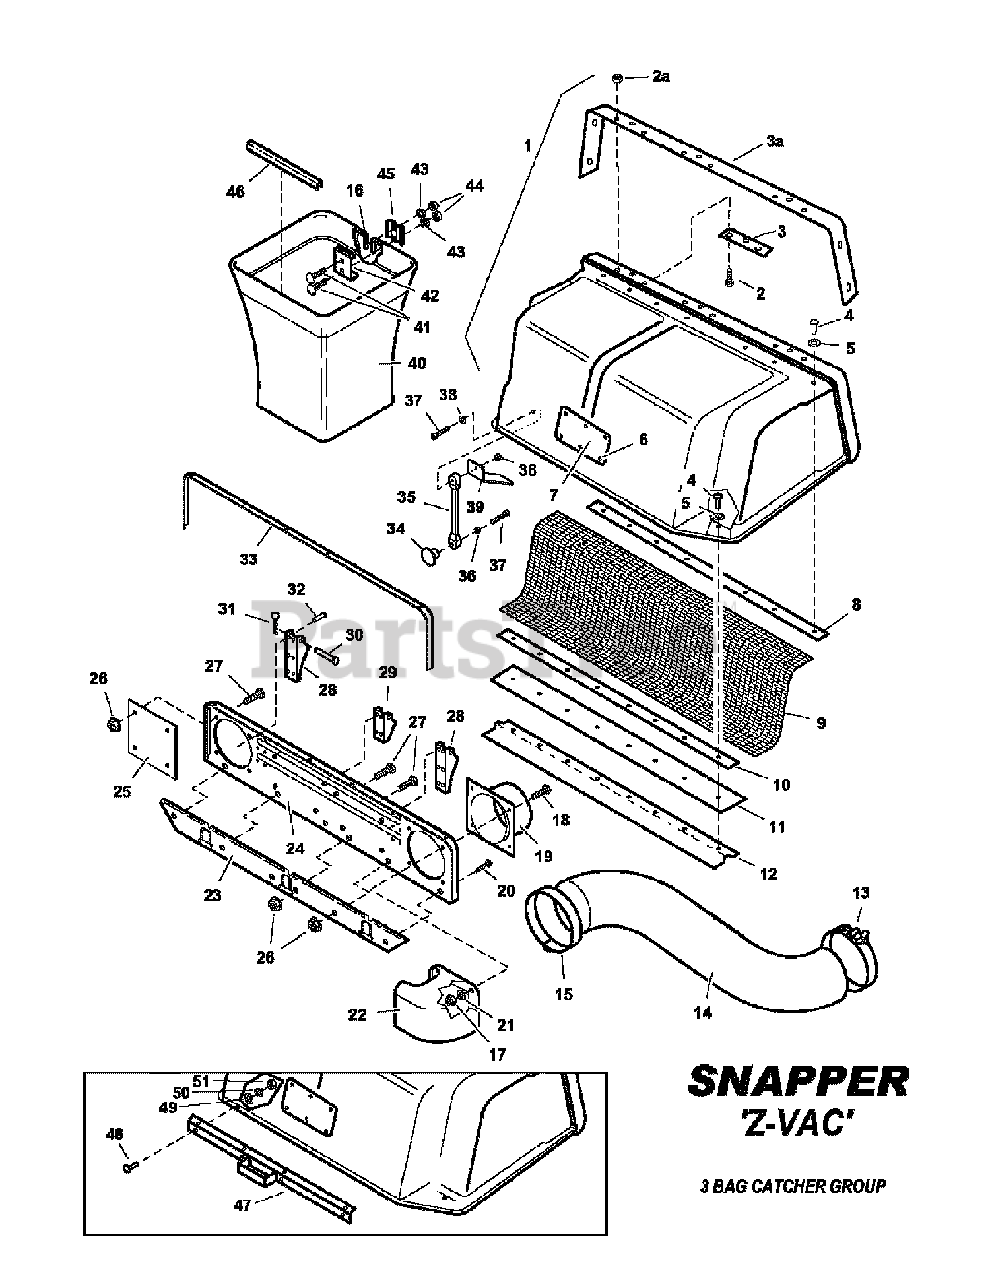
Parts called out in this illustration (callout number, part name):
1	ASSEMBLY, Cover & Screen
2	SCREW, 1/4-20 x 3/4" Hex Head Cap, GR5
2	SCREW, 1/4-20 x 5/8" Hex Head Cap, GR5
2A	NUT, 1/4-20 Hex Flange Lock, GR5
3	WELDMENT, Hinge
3A	STIFFENER, Hinge
4	POP RIVET, 3/16 x .565,Aluminum
5	* WASHER, Rivet .188 (.20 I.D. x .500 O.D.)
6	CLIP, Canoe
7	DECAL, Safety, Grass Bag
8	CLAMP
9	SCREEN, Catcher
10	CLAMP, Seal
11	SEAL, Catcher Top
12	ANGLE, Screen
13	HOSE, CLAMP Lower, Fast Vac
14	HOSE, Snapper Fast Vac
15	HOSE CLAMP, Upper
16	HOOP, Grass Bag
17	NUT, 5/16-18 Hex Nyloc
18	SCREW, 5/16-18 x 1" Hex Head Cap, GR5
19	ADAPTER, Hose (weldment)
20	SCREW, 1/4-20 x 1/2" Hex Washer Self-Tap
21	* WASHER, 5/16" Flat
22	DEFLECTOR, Grass Bag
23	ASSEMBLY, Channel
24	WELDMENT, Backplate
25	COVER, Backplate
26	NUT, 5/16-18 Hex Flange Lock, GR5
27	SCREW, 5/16-18 x 3/4" Hex Head Cap, GR5
28	HINGE
29	HINGE
30	PIN, 3/8 x 2-3/4" Clevis
31	PIN, 1/8 x 1-1/4" Cotter
32	* RIVET
33	SEAL, Catcher Top
35	STRAP, Rubber
36	NUT, #10-32 Hex Nyloc
37	SCREW, #10-32 x 1-1/2 Hex Washer Head Machine
38	WASHER, .19 x .38 x .06 Flat
39	COVER SUPPORT
40	GRASS BAG
41	BOLT, 5/16-18 x 3/4" Square Neck Carriage, GR5
42	HANGER, Grass Bag
43	WASHER, 5/16 Split Lock
44	NUT, 5/16-18 Hex
45	CLAMP, Grass Bag
46	TUBE CLIP, Grass Bag
47	COVER, Handle (weldment)
48	SCREW, #8-32 x 1/2" Cross Recess Pan Head
49	* WASHER, #8 Flat
50	WASHER, #8 External Tooth Lock
51	* NUT, #8-32 Hex Machine, GR 2B
